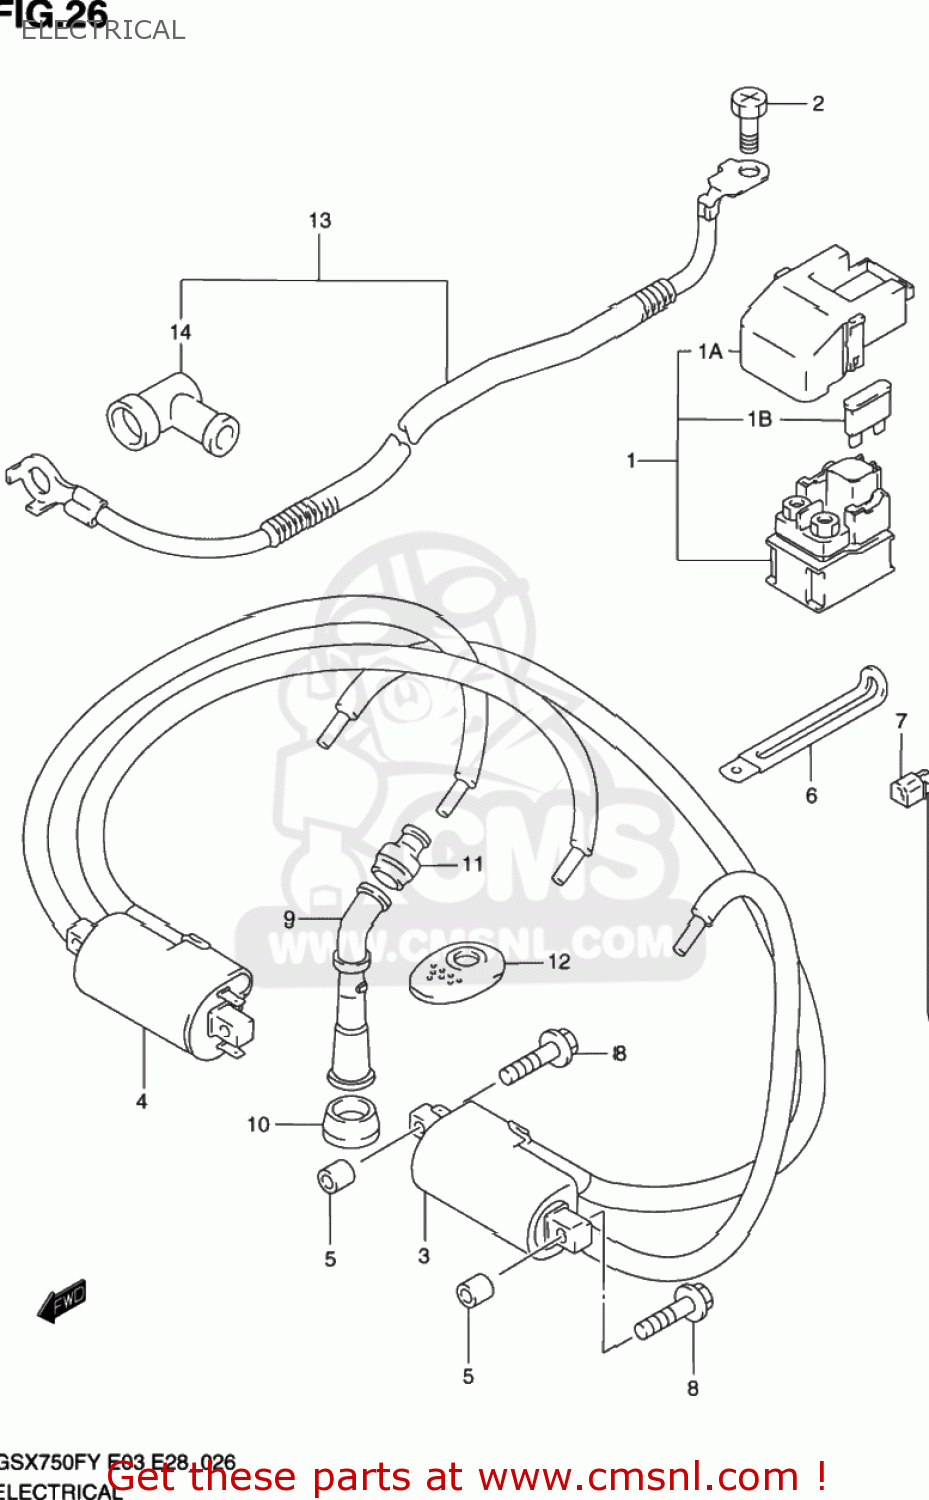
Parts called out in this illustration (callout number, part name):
1	RELAY ASSY,STARTING MOTOR
1A	COVER,RELAY ASSEMBLY
1B	FUSE(30A)
2	SCREW(6X8)
3	COIL ASSY,IGNITION
4	COIL ASSY,IGNITION
5	SPACER(6.2X12X14)
6	CLAMP(L:65)
7	CLAMP(L:165)
8	BOLT (6X45)
9	CAP,SPARK PLUG
10	SEAL,SPARK PLUG CAP
11	SEAL,HIGH TENSION CORD
12	COVER,SPARK PLUG CAP
13	WIRE,BATTERY MINUS
14	CAP,STARTER MOTOR LEAD
